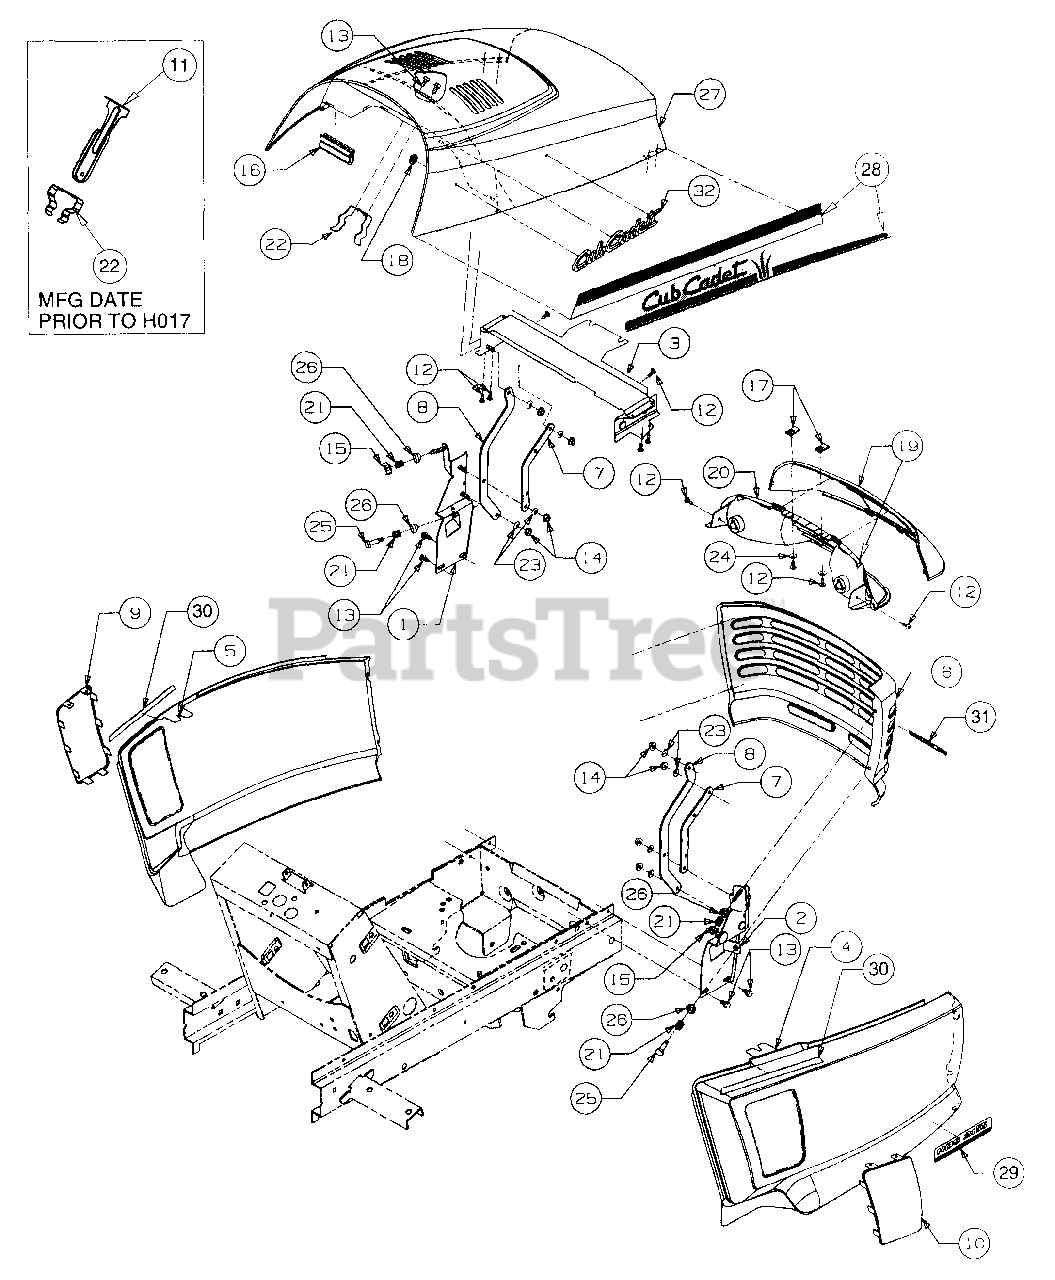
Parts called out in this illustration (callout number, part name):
1	Bracket, Grille LH
2	Bracket, Grille RH
3	Bracket, Upper Hood
4	Panel, RH Side
5	Panel, LH Side
8	Link, Long Hood
9	Screen, LH Panel
10	Screen, RH Panel
11	Guide, Hood
12	Screw, Truss Mach Tapp, #10 x .50
13	Screw, Hex Wash Hd Tapp, 1/4 x .50
14	Nut, Hex Flange Lock, 1/4-20
15	Nut, Wing, 1/4-20
16	Seal, Heat Baffle
17	Nut, U-Type Speed, #10
18	Retainer, Push Nut
19	Headlight Assembly
20	Headlight Assembly
21	Spring, Compression, .50 OD x .50 Lg
22	Spring, Hood Latch
23	Washer, Spring, .265 x .562 x .025
24	Washer, Flat, .218 x .62 x .063
25	Bolt, Shoulder, .31 Dia x .75 Lg
26	Bushing, Tapered
27	Hood, Series 2000
28	Graphic, Hood, RH
29	Graphic, HDS 2155
30	Strip, Protective
31	Graphic, Warning HOT
32	Script w/Studs, Cub Cadet
